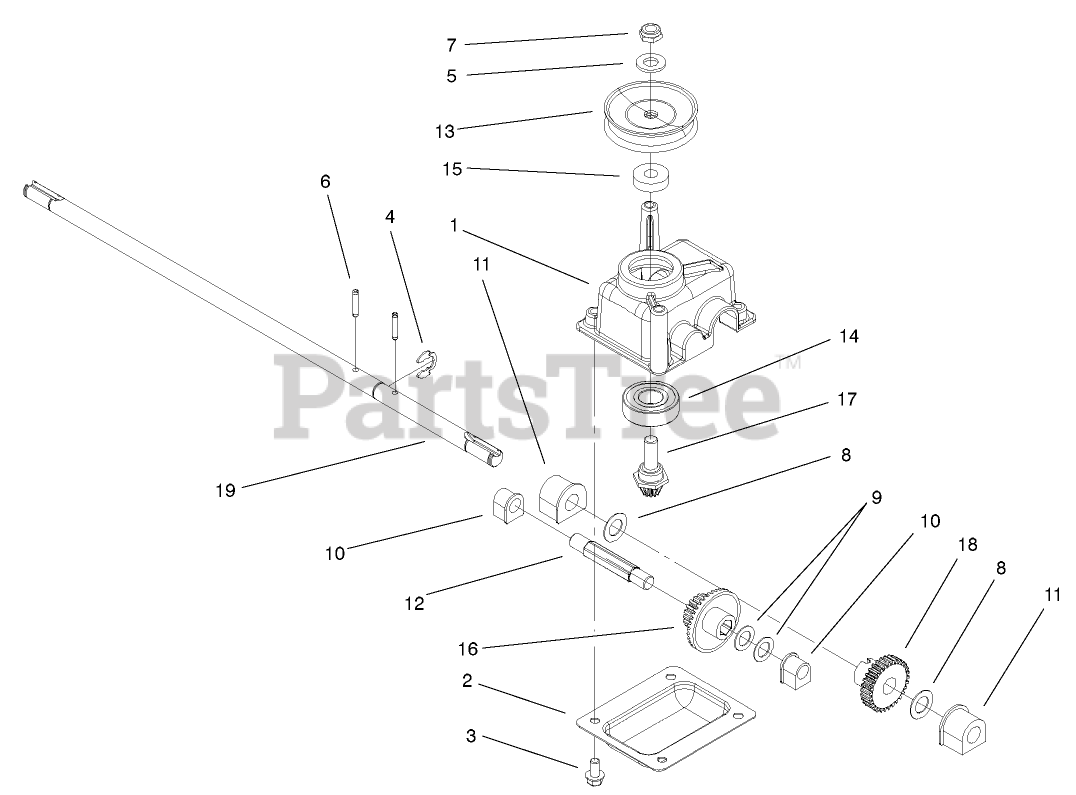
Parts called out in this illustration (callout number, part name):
1	CASE-GEAR
2	COVER-CASE, GEAR
3	SCREW-HWH
4	RING-RETAINING
5	WASHER-FLAT
6	PIN-GROOVE
7	NUT-HEX
8	WASHER-PLAIN
9	WASHER-THRUST
10	BUSHING
11	BUSHING
12	SHAFT-INTERMEDIATE
13	PULLEY-HALF
14	BEARING-BALL
15	SPACER
16	GEAR-19T SPUR, 37T BEVEL
17	GEAR-PINION, BEVEL
18	GEAR-30T
19	SHAFT-OUTPUT
